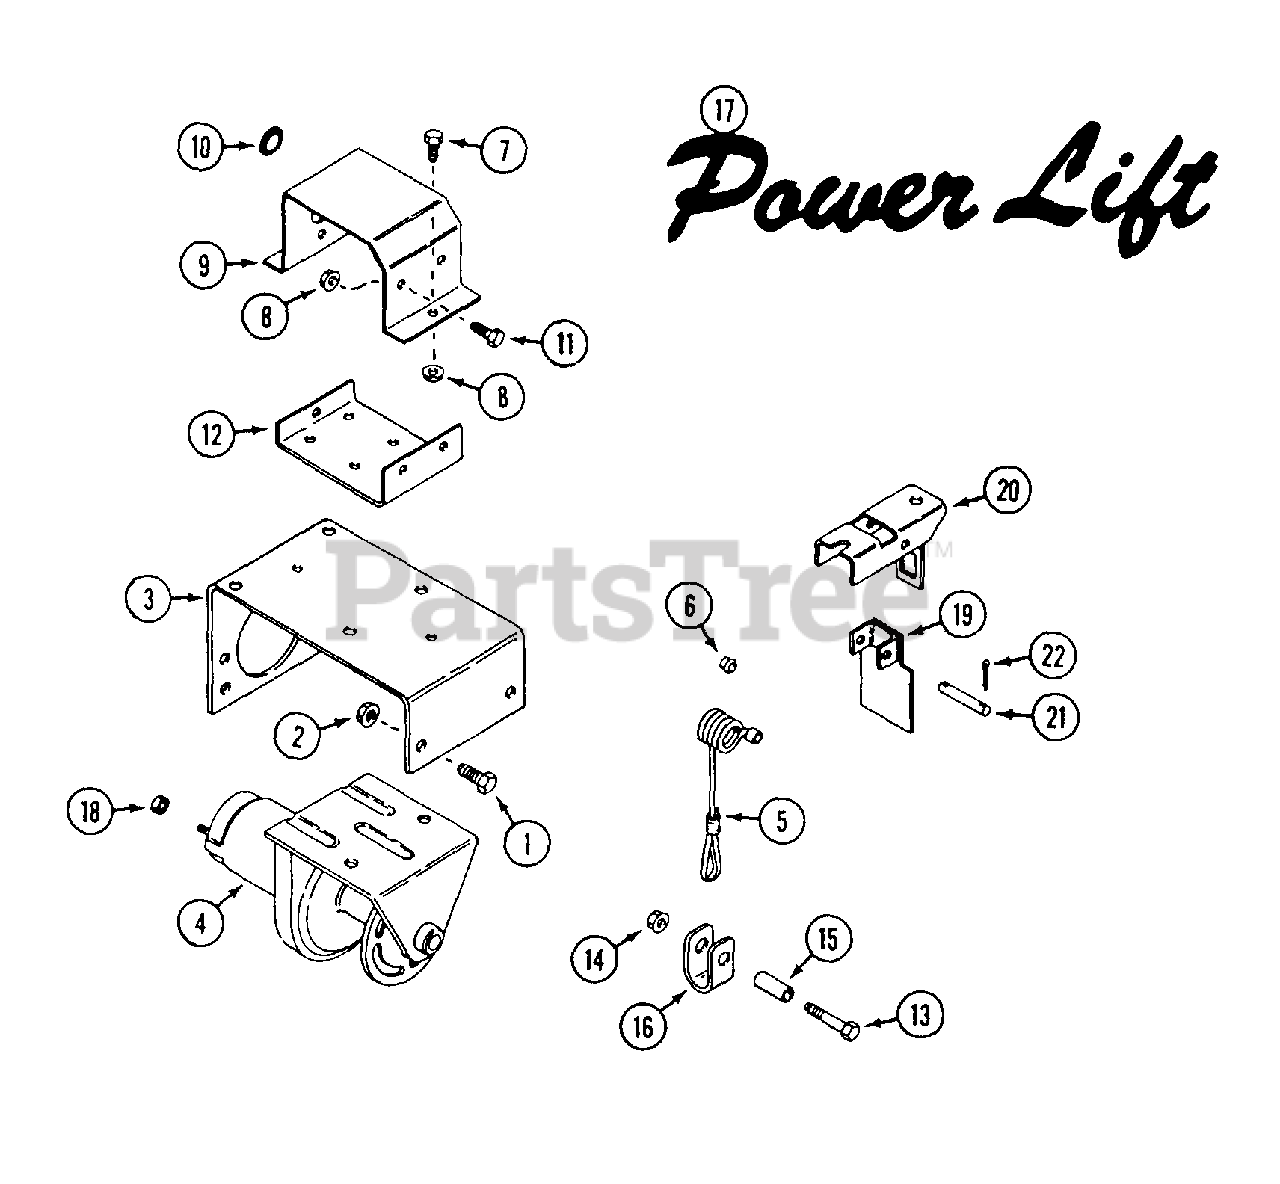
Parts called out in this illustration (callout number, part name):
1	BOLT - 3/8" - 16 x 1"
2	NUT - 3/8" - 16 flange lock
3	MOUNT - winch
4	WINCH - deck lift
6	PIN - cable keeper
7	BOLT - 1/4" - 20 x 3/4"
8	NUT - 1/4" - 20 flange lock
9	COVER - solenoid
10	GROMMET - 1" x 7/8"
11	BOLT - 1/4" - 20 x 1/2"
12	MOUNT - solenoid
13	BOLT - 3/8" - 16 x 2"
14	NUT - 3/8" - 16 lock
17	DECAL "Power Lift"
18	NUT - #10 - 32
20	MOUNT - trip arm
22	PIN - cotter 1/16" x 5/8"
